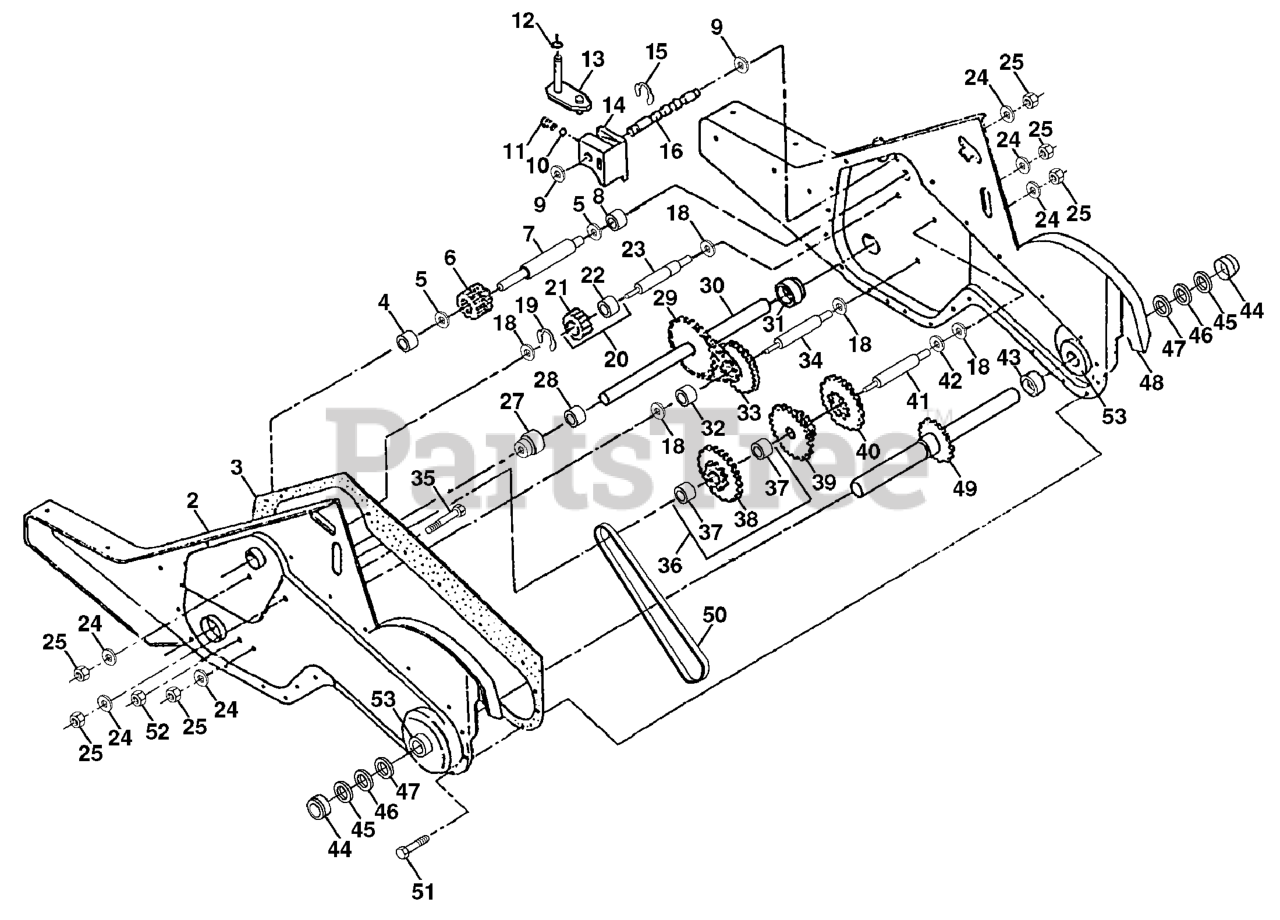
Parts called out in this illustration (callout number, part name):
1	TRANSMISSION ASSEMBLY
2	GEARCASE LH W/BRG
3	GASKET TI
4	NEEDLE BRNG LT
5	THRUST WASHER
6	GEAR.PINION.INPUT
7	SHAFT.INPUT."D".TILLER
8	BEARING TI
9	WASHER SEAL CRT
10	STEEL BALL KIT
11	SPRING-SHIFT CRT
13	BRACKET ASM.SHIFT.CRT
14	SHIFT FORK TI
16	SHIFT SHAFT
20	GEAR ASSY CRT
21	GEAR-REV IDLR CRT
22	NEEDLE BEARING TI
24	LOCKWASHER
25	NUT.ASF.HEX.7/16
27	BEARING, SHAFT LH CRT
30	SHAFT ASSY CRT
31	BEARING, SHAFT RH CRT
33	SPRCKT 8 GEAR CRT
34	SHAFT.SECONDARY.REDUCTION.CRT
35	SCRW WHIZ LOK CRT
36	SPROCKET ASSY W/ BRG
37	BEARING
38	SPROCKET TINE
41	SHAFT.REDUCTION.TILLER
42	BRNG RACE T
44	CUP
45	RING.SPIRAL.CRT.TILLER
48	GEARCASE RH W/BRG
49	TINE SHAFT
50	CHAIN.TILLER
51	SCREW CRT
52	NUT
53	BEARING KIT
